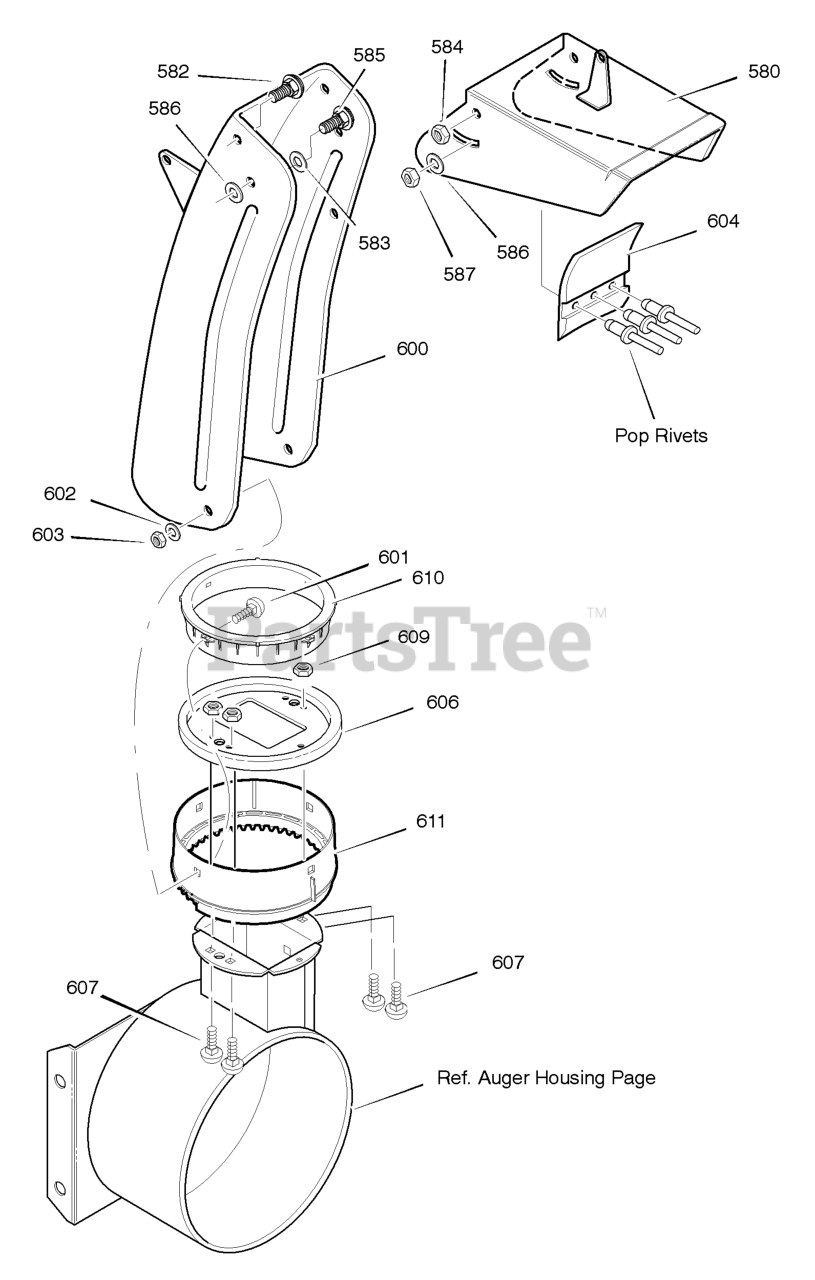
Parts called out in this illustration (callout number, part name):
580	CHUTE, UPPER W/REMOTE
582	SCREW, 5/16-18 x 0.75
583	PLASTIC WASHER
584	NUT, 5/16-18
585	SCREW, 5/16-18 x 0.75
586	PLASTIC WASHER
587	NUT, 5/16-18
600	CHUTE, LOWER W/REMOTE
601	BOLT, 5/16-18 x 1.00
602	WASHER, FLAT
603	NUT, 5/16-18
606	CHUTE COLLAR
607	BOLT, 1/4-20 x 0.75
609	NUT, 1/4-20
610	RETAINER, RING INNER
611	RETAINER, RING OUTER
